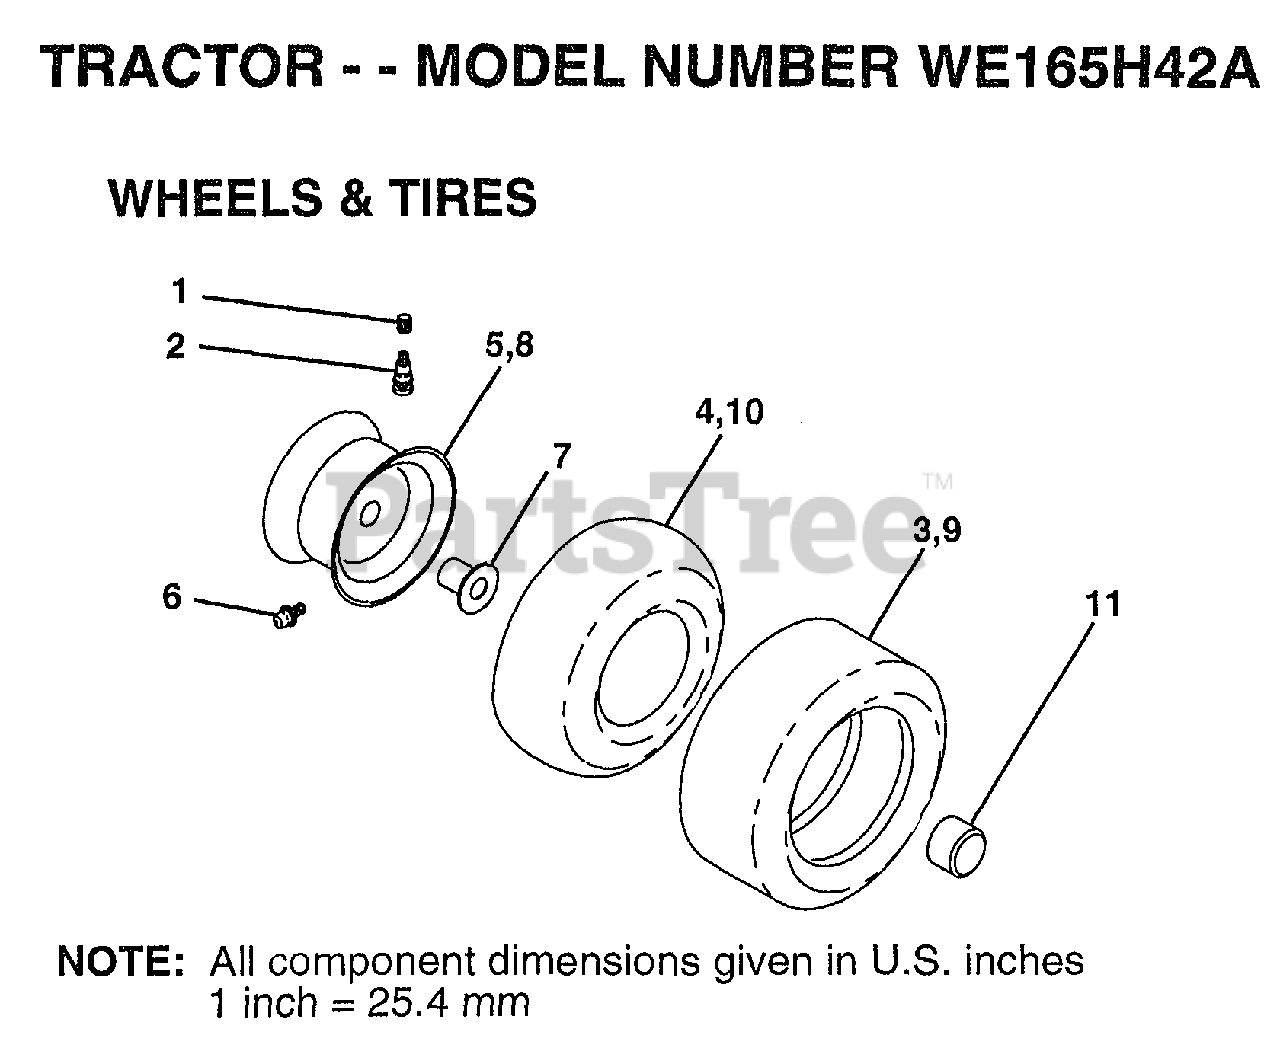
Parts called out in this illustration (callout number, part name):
1	VALVE CAP
2	VALVE STEM LT
4	TUBE.5.3/4.5/6
5	"RIM ASM 6"" FRT"
6	FITTING LT
7	"FLANGE, BEARING"
8	"RIM AS 8"" REAR"
9	TIRE.20X8-8
10	TUBE.18X9.5-8
11	HUB CAP
